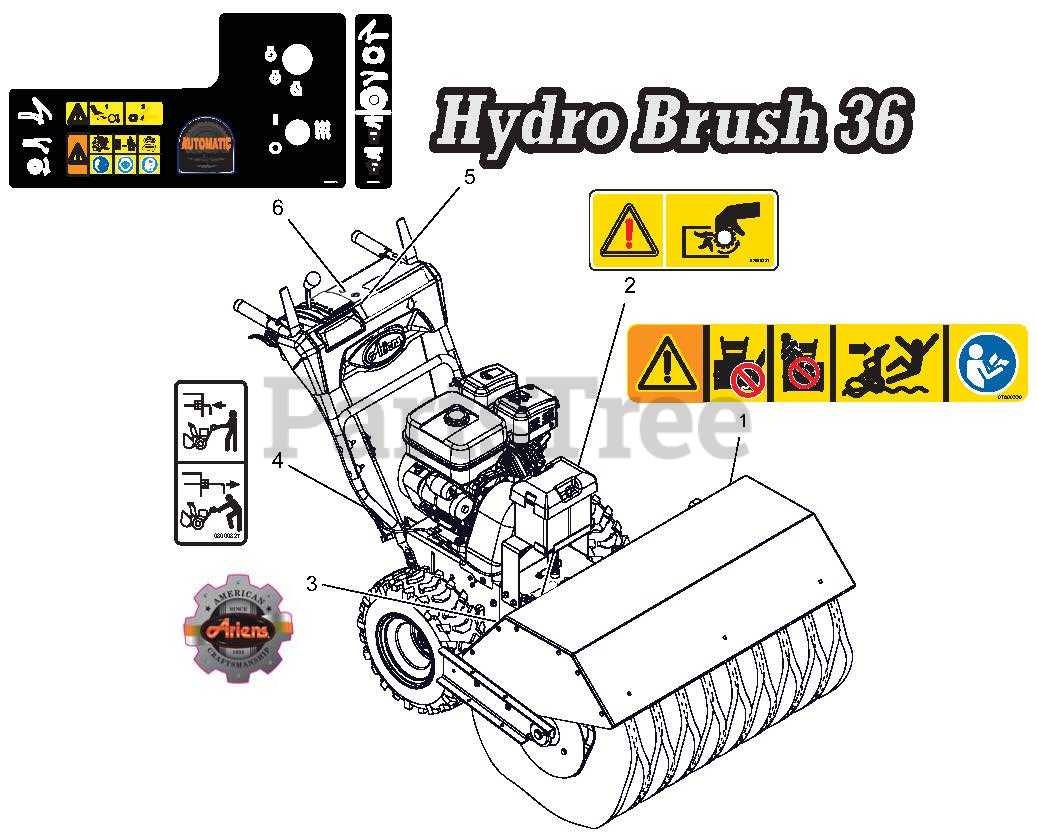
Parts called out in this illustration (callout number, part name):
1	DECAL, DANGER -POWER BRUSH-CE
2	DECAL, PTO WARNING
3	DECAL, ARIENS HERITAGE-LARGE
4	DECAL, BYPASS
5	DECAL, HYDRO BRUSH 36
6	DECAL, CONTROL - BRUSH 12V
